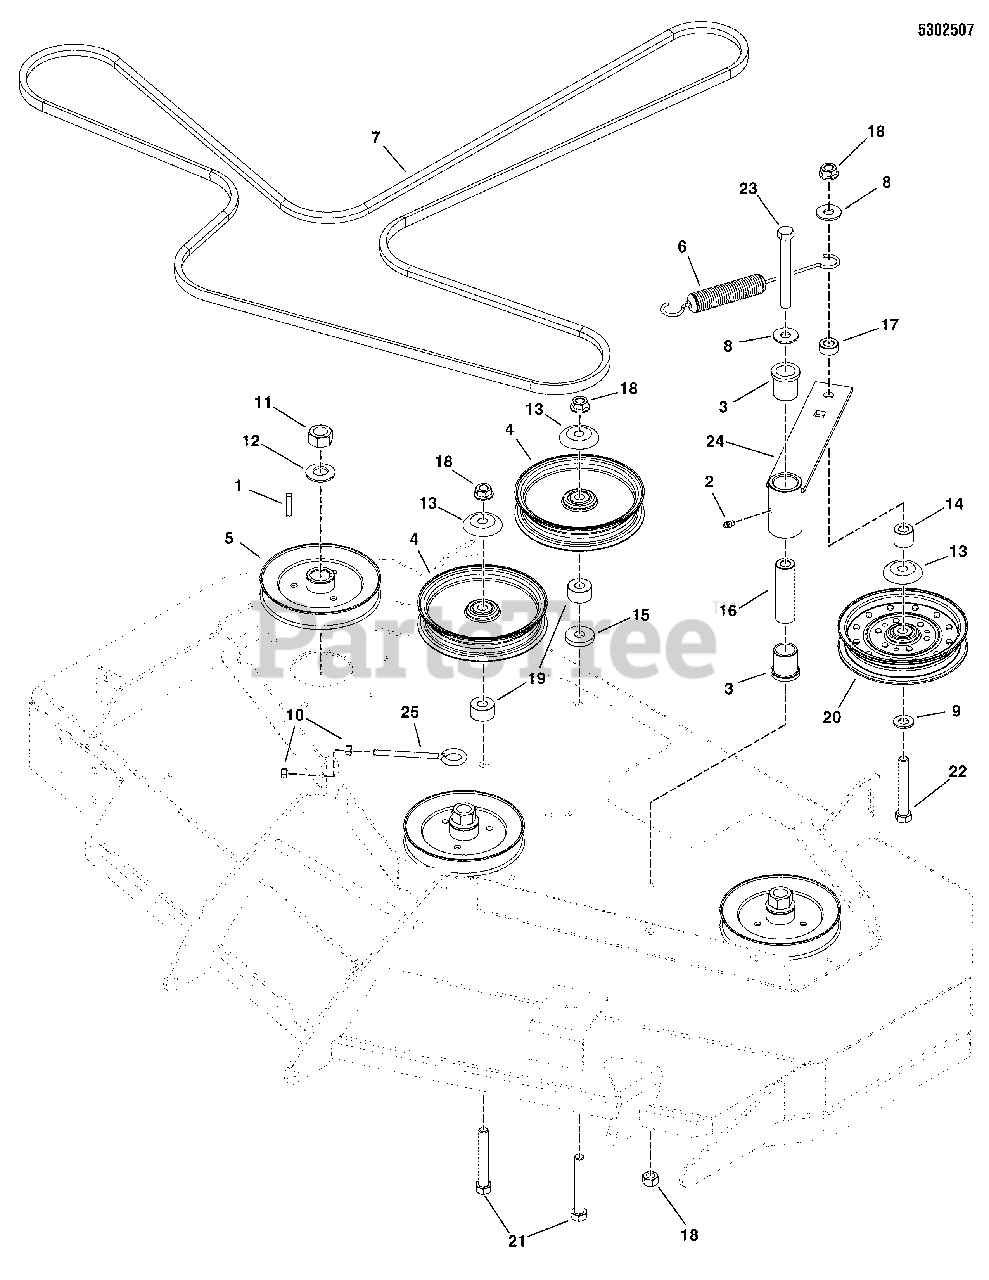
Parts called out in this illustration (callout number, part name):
1	KEY, 1/4 SQ. X 1-1/4
2	GREASE FITTING, 1/4-28 STRAIGHT
3	BUSHING, FLANGE
4	*PULLEY, FLAT IDLER, 6-3/4"
5	PULLEY, 5.926 OVER BALL
6	SPRING, EXTENSION, SWIVEL END
7	BELT, 5V, 163.40EL, LG ARAMID, WRPD, RC
8	WASHER, 1/2 USS
9	WASHER, 1/2 SAE
10	NUT, 3/8-16 HEX
11	NUT, 3/4-16 HEX
12	WASHER, 3/4 BELLEVILLE
13	SHIELD, PULLEY BEARING
14	SPACER, .52 X 1.00 X .88
15	WASHER, .53 X 1.50 X .25
16	SPACER, .52 X 1.00 X 3.50
17	SPACER, .52 X 1.00 X .44
18	NUT, 1/2-13 HEX NYLOCK FLANGE
19	SPACER, .52 X 1.25 X .70
21	BOLT, 1/2-13 X 2-3/4 GD5
22	BOLT, 1/2-13 X 3-1/2 GD5
23	BOLT, 1/2-13 X 4-1/2 GD5
24	ASSM, IDLER ARM - BLK - 5407039A (SV)
25	EYE BOLT, 3/8-16 X 6, 3.0 THRD, 1 EYE
